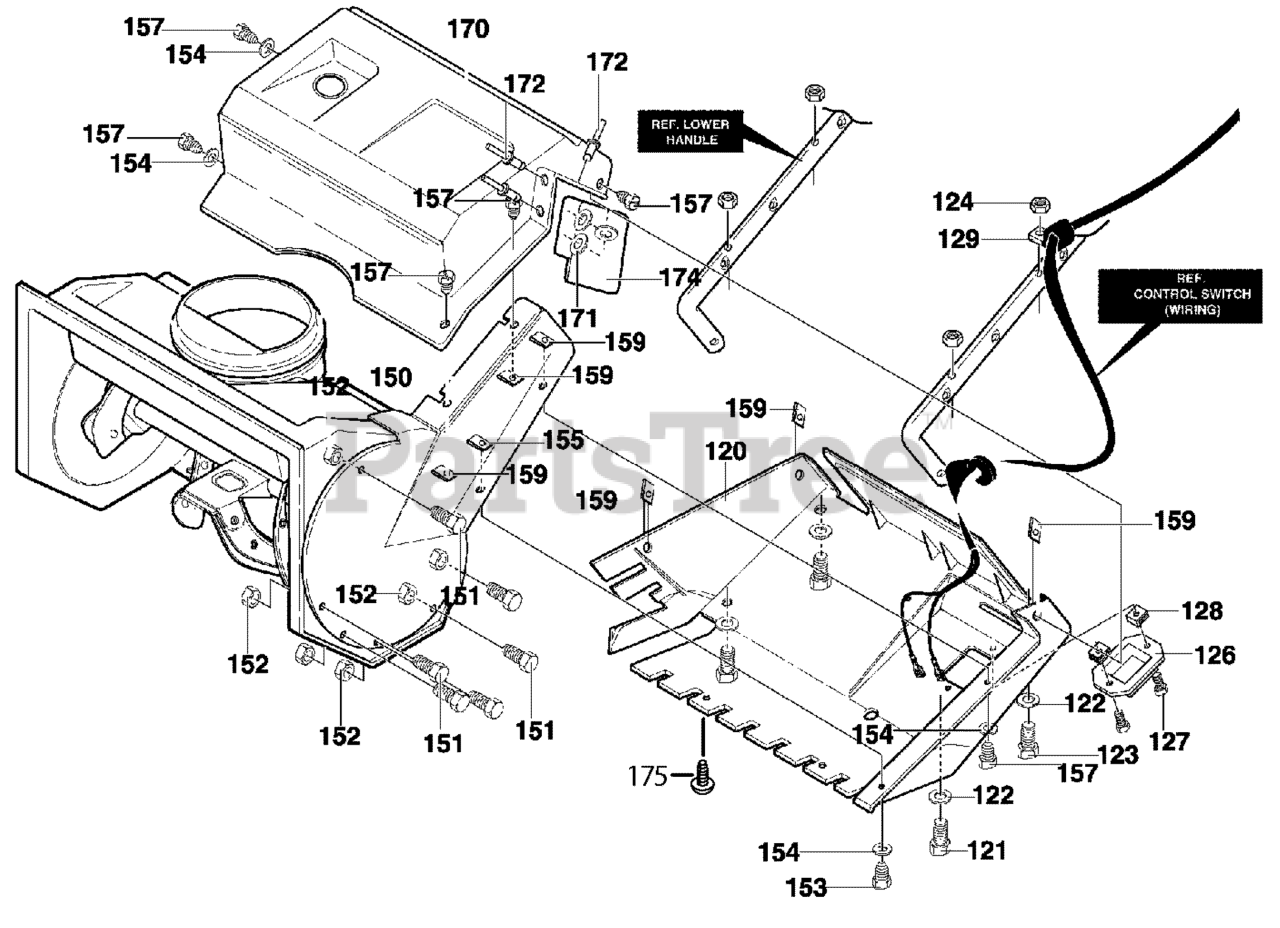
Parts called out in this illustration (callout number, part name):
120	BOTTOM COVER
121	SCREW, 1/4-20 x 1.25
122	FLATWASHER
123	SCREW, 1/4-20 x 1.50
124	NUT, 1/4-20
126	CABRURATOR COVER
127	SCREW, 1/4-14 x .75
128	NUT, 1/4-10
129	CABLE CLIP
150	COVER, BELT
151	SCREW, 10-24 x .50
152	NUT, #10-24
153	SCREW, 1/4-20 x .50
154	FLATWASHER
155	NUT, 1/4-20
157	SCREW, 1/4-14 x .75
159	NUT, 1/4-10
170	TOP COVER
171	FLATWASHER
174	SIDE COVER
175	SCREW 10-14 x 0.63
